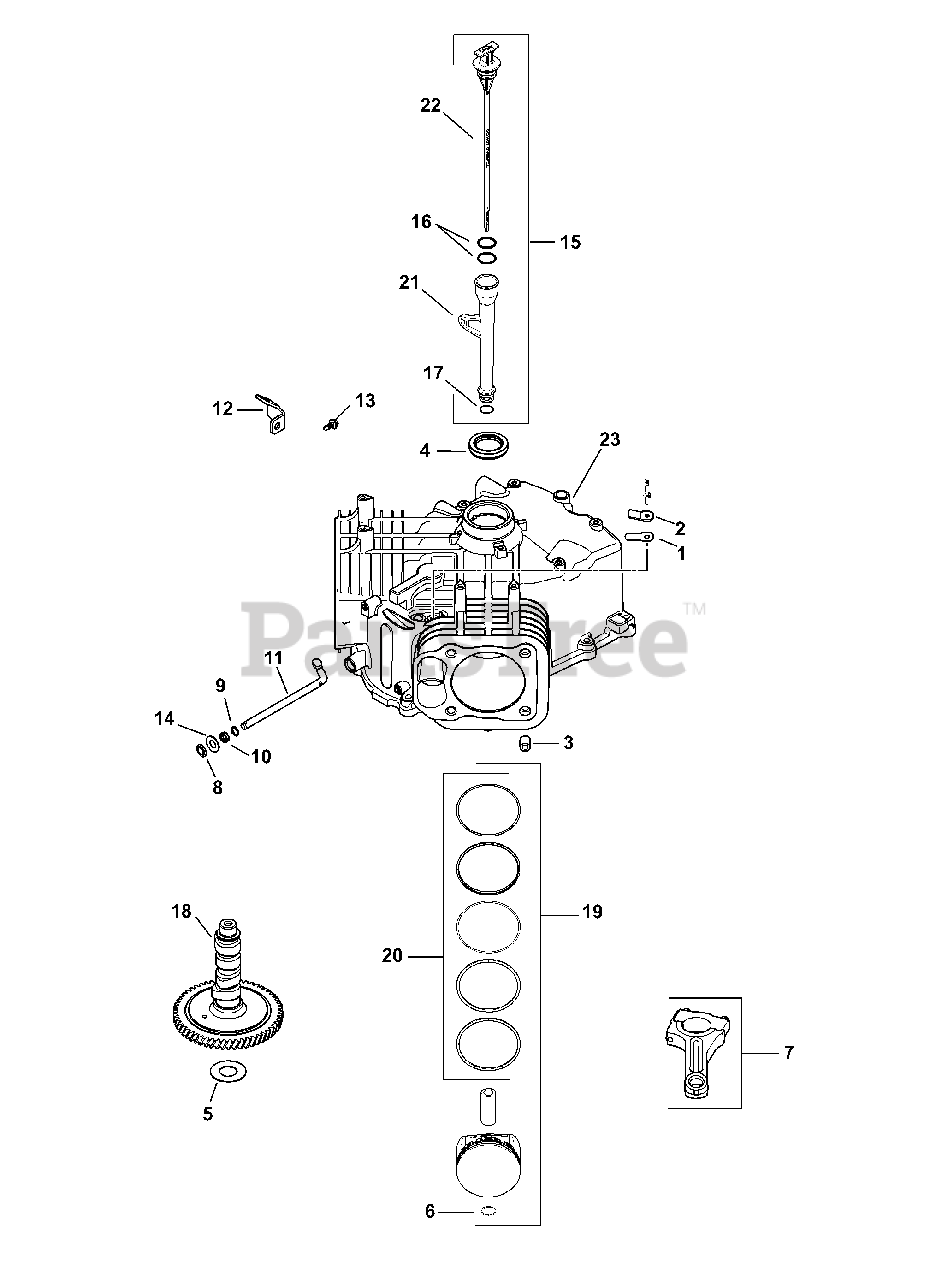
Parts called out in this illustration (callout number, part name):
1	Breather Reed
2	Breather Reed Retainer
4	Oil Seal, 1.78 x 1.26
5	Camshaft Shim (White, .028)
5	Camshaft Shim (Blue, .03)
5	Camshaft Shim (Red, .032)
5	Camshaft Shim (Yellow, .034)
5	Camshaft Shim (Green, .036)
5	Camshaft Shim (Gray, .038)
5	Camshaft Shim (Black, .04)
6	Piston Pin Retainer
7	Connecting Rod (STD)
8	Ring Retainer
9	Flat Washer, 11/32
10	Governor Cross Shaft Seal
11	Governor Cross Shaft
12	Oil Fill Tube Bracket
13	Flange Screw, M5 x .8 x 13
14	Flat Washer, 9mm
15	Dipstick & Tube Kit
17	Lower Oil Fill Tube O-Ring
18	Camshaft Assembly
19	Piston W/ Ring Kit (STD)
19	Piston W/ Ring Kit (.08)
19	Piston W/ Ring Kit (.25)
20	Ring Set (STD)
20	Ring Set (.08)
20	Ring Set (.25)
21	Tube Assembly
22	Dipstick Assembly
23	Crankcase
